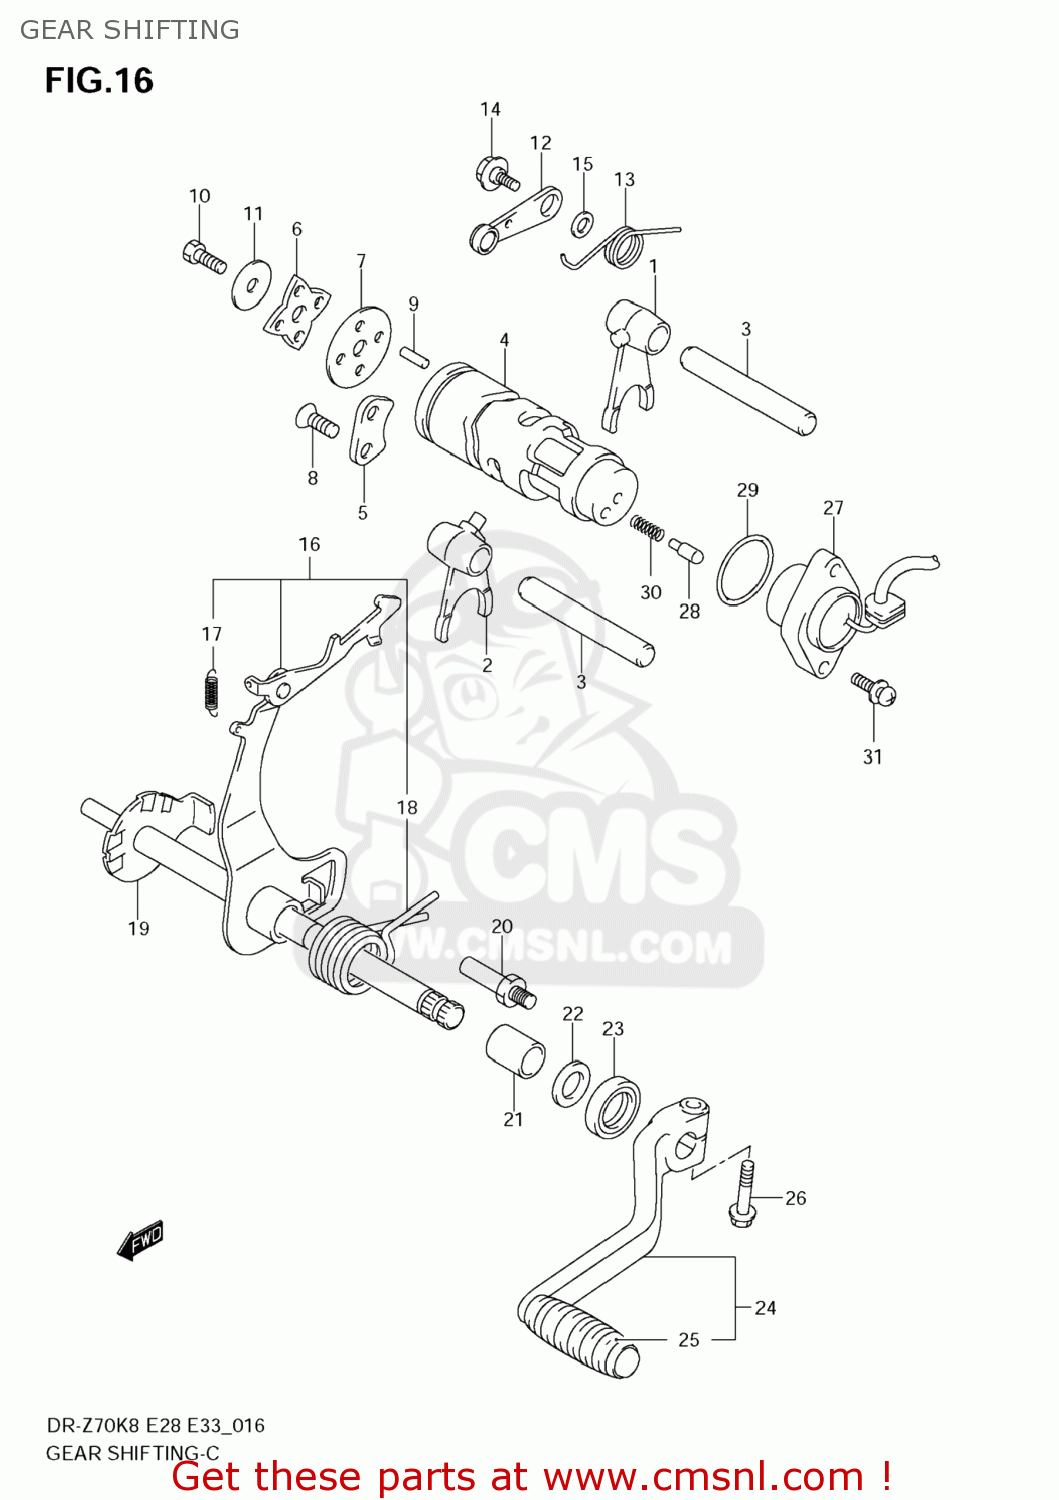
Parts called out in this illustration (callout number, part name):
1	FORK,GEAR SHIFT NO.1
2	FORK,GEAR SHIFT NO.2
3	SHAFT,GEAR SHIFT FORK
4	CAM,GEAR SHIFT
5	RETAINER,SHIFT CAM
6	PLATE,GEAR SHIFT CAM STOPPER
7	GUIDE,SHIFT CAM STOPPER PIN
8	SCREW(6X16)
9	ROLLER(4X13.8)
10	BOLT
11	WASHER
12	STOPPER,SHIFT CAM
13	SPRING,SHIFT CAM STOPPER
14	BOLT(6X14.3)
15	WASHER
16	ARM ASSY,GEAR SHIFT
17	SPRING
18	SPRING
19	SHAFT,GEAR SHIFT
20	STOPPER,GEAR SHIFT ARM
21	SPACER(12X16X20)
22	SHIM(12X20X1)
23	OIL SEAL
24	LEVER ASSY,GEAR SHIFT
25	RUBBER,GEAR SHIFT PEDAL
26	BOLT
27	BASE ASSY,NEUTRAL SW TERMINAL
28	PIN(5X15.5)
29	O RING(D:2.4,ID:26.2)
30	SPRING
31	SCREW
